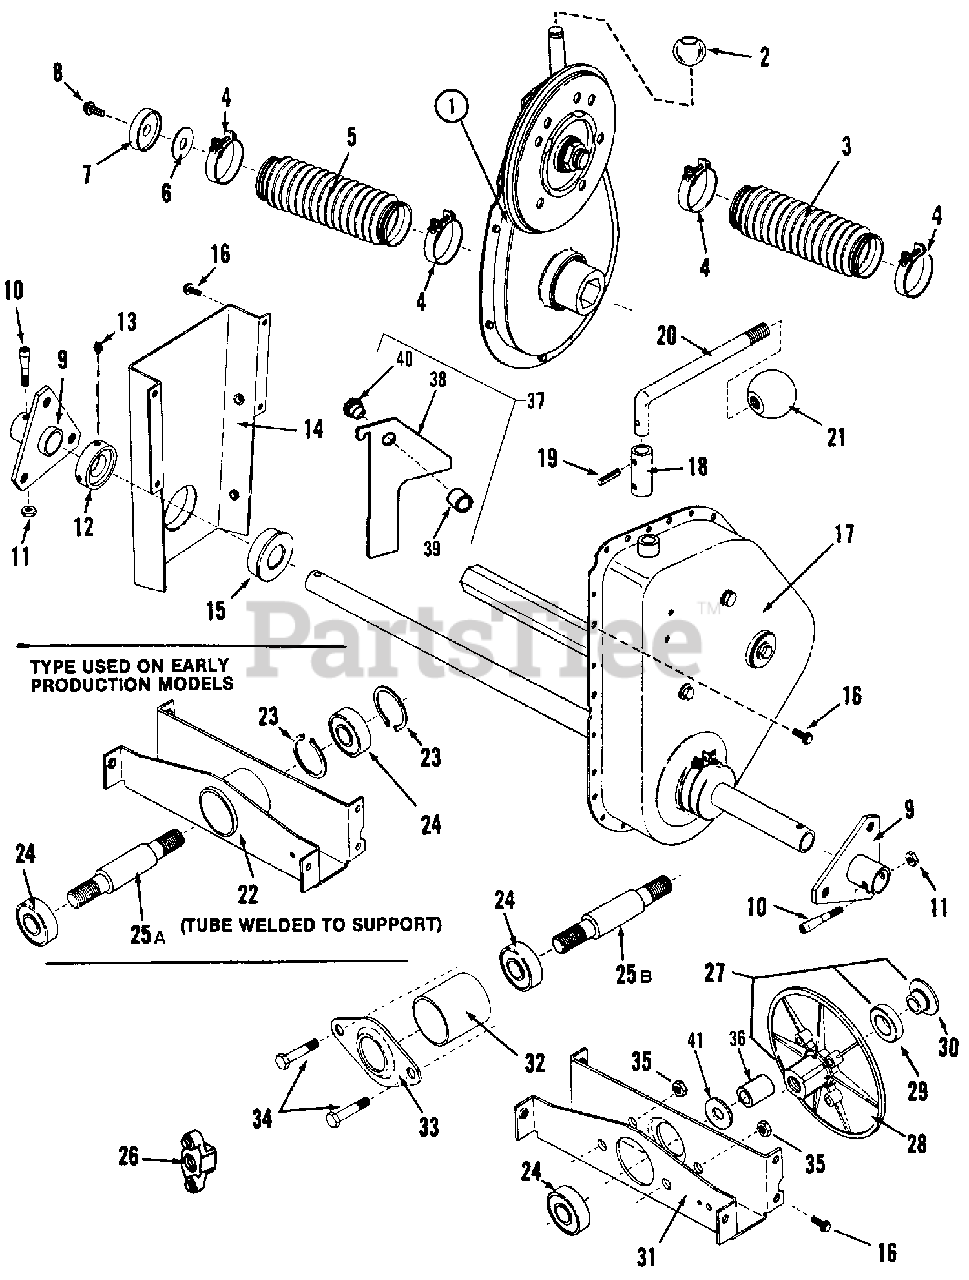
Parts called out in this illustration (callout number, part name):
1	PRIMARY CASE
2	BUSHING, Primary Clutch
3	BOOT, Left Side Oil seal
4	CLAMP, Boot
5	BOOT, Oil Seal
6	WASHER, Thrust
7	SPACER, Hex Tube
8	SCREW, 3/8-16 x 1" Hex Washer Self-Tap
9	HUB, Rear Wheel
10	BOLT, Tapered
11	NUT, 5/16-24 Hex Lock
12	LOCK-COLLAR
13	SETSCREW, 5/16-18 x 5/16"
14	ASSEMBLY, Axle Support
15	BEARING, Ball
16	SCREW, 5/16-18 x 5/8" Hex Washer Self-Tap
17	ASSEMBLY, Transmission
18	COUPLING, Shift Lever
19	ROLL-PIN, 3/16 x 3/4"
20	LEVER, HI-LO Shifter
21	KNOB, Shifter Ball
22	SUPPORT, Bearing (NLA)(Use item #'s 25B - 34)
23	RING, Retaining
24	BEARING, Ball
25A	SPINDLE, Drive Disc (5.040")
25B	SPINDLE, Drive Disc 1985 (6.040")
26	HUB, Flex Coupling
27	ASSEMBLY, Drive Disc
28	DISC, Drive
29	BEARING, Ball
30	BUTTON, Center
31	SUPPORT, Bearing
32	TUBE
33	RETAINER
34	SCREW, 5/16-18 x 3" Hex Head
35	NUT, 5/16-18 Hex Center Lock Grade B or 5
36	SPACER, Drive Disc
37	KIT, Drive Disc Adjustment Gauge
38	GAUGE PLATE, Drive Disc Adjustment
39	SHAFT EXTENSION
40	PLUG, Plastic 5/8-18
41	SHIM WASHER,
